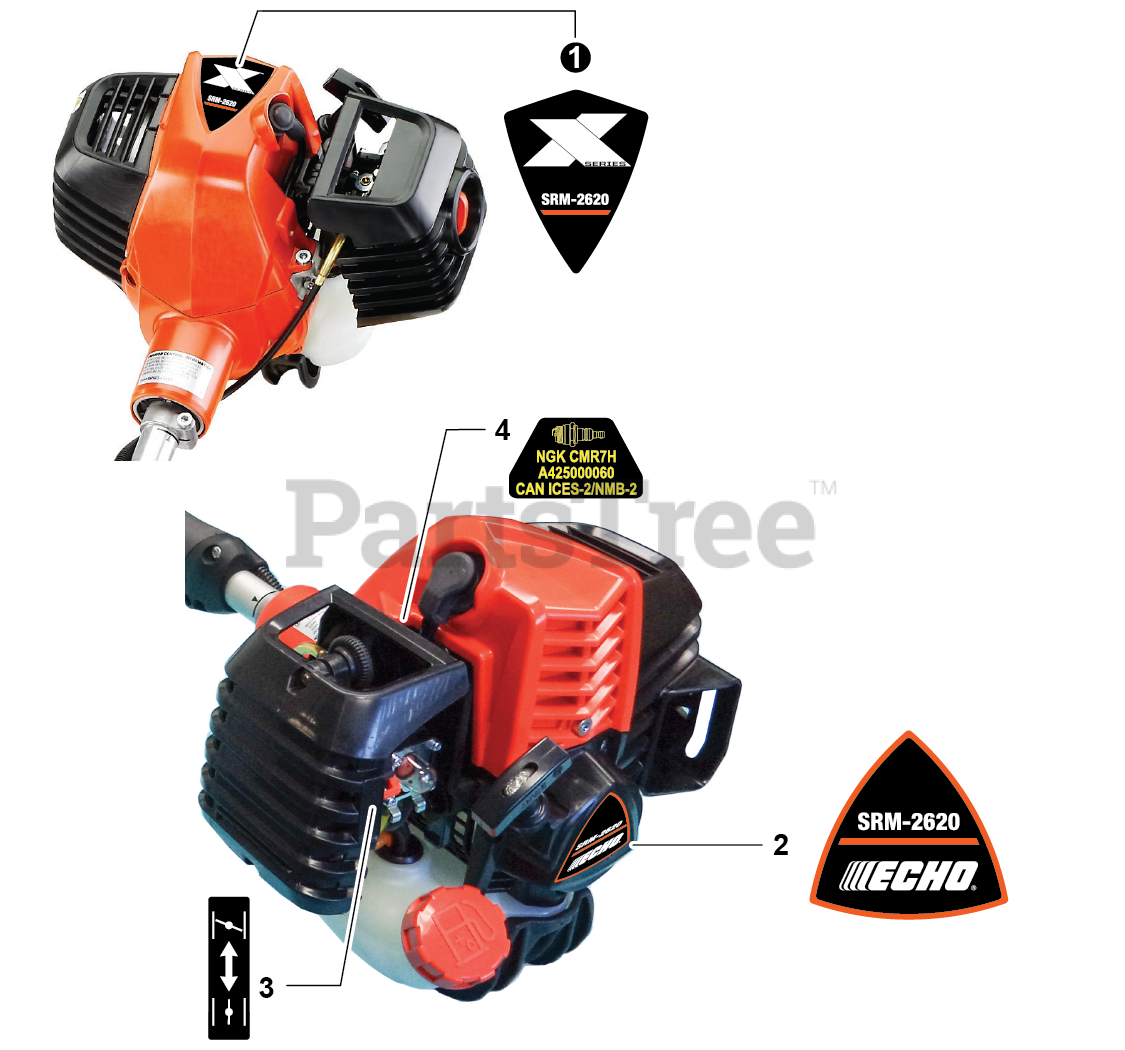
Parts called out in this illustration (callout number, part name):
1	LABEL - MODEL SRM-2620
2	LABEL - STARTER - SRM-2620
3	LABEL - CHOKE
4	LABEL - SPARK PLUG - CMR7H
